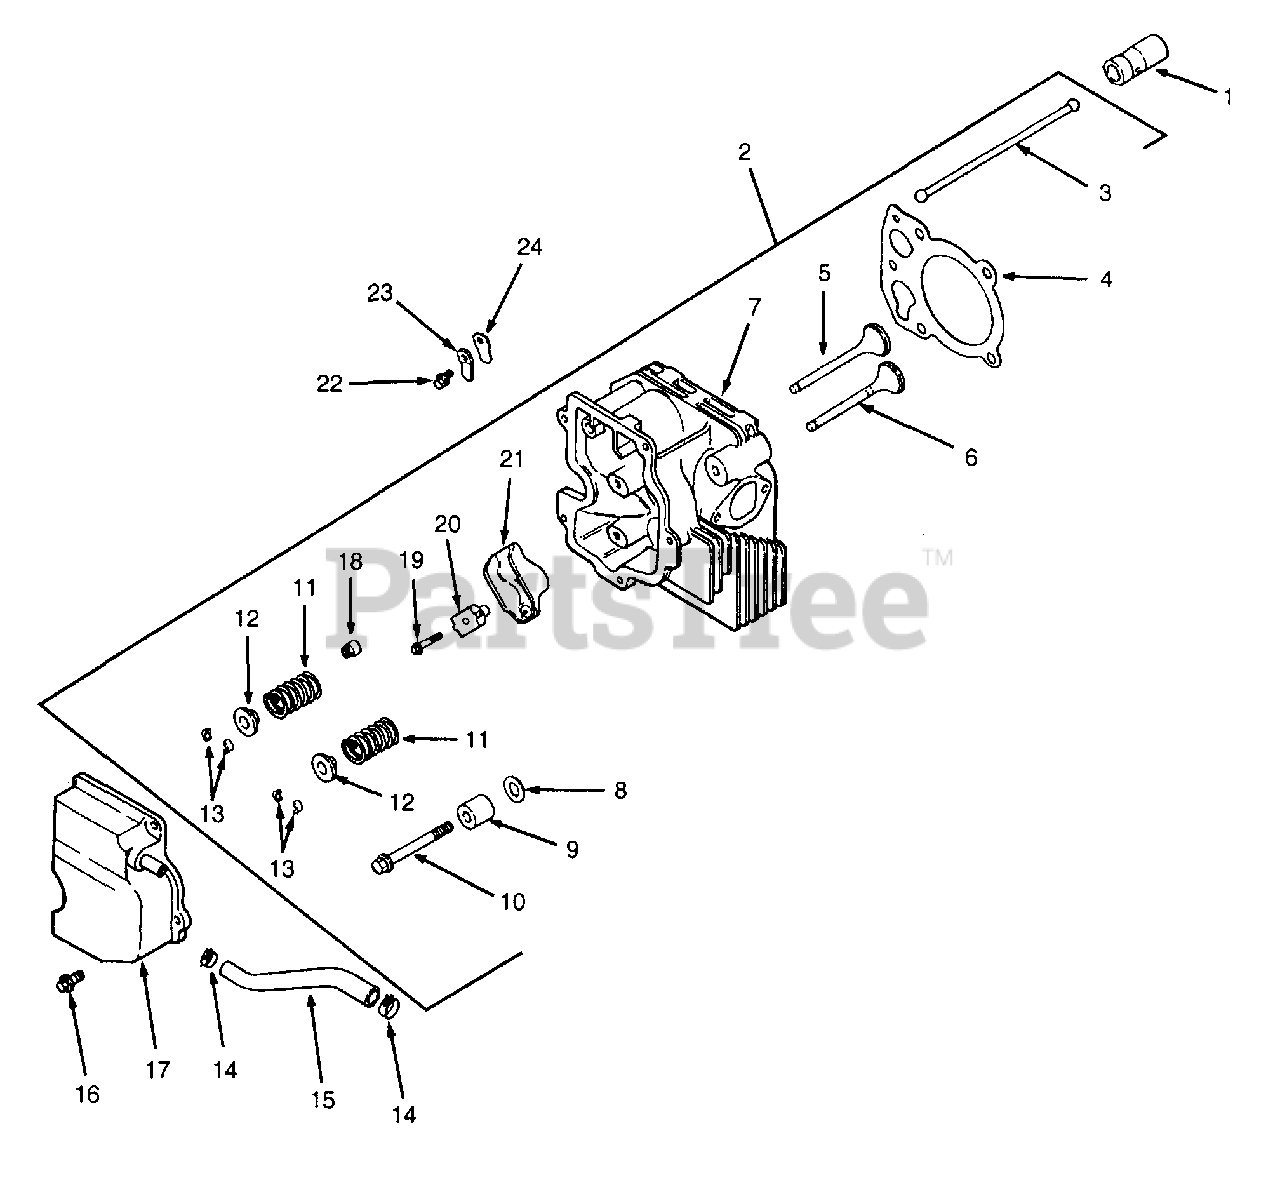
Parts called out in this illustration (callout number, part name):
1	Lifter, Valve
2	Kit, Cylinder Head
3	Rod, Push
4	Gasket, Cylinder Head
5	Valve, Intake, Std.
6	Valve, Exhaust, Std.
7	Head, Cylinder
8	Washer, Plain 13/32
9	Spacer, Head Bolt Exhaust Port
10	Screw, Hex Flange, M10 x 1.5 x 81
11	Spring, Valve
12	Cap, Valve Spring
13	Kit, Retainer
14	Clamp, Hose
15	Hose, Breather
16	Screw, Hex Flange, M6 x 1.0 x 20
17	Cover, Valve w/Nipple
18	Seal, Valve Stem
19	Screw, Hex Flange, M6 x 1.0 x 34
20	Pivot, Rocker Arm
22	Screw, Hex Flange, M5 x 0.8 x 10
23	Retainer, Breather Reed
24	Reed, Breather
